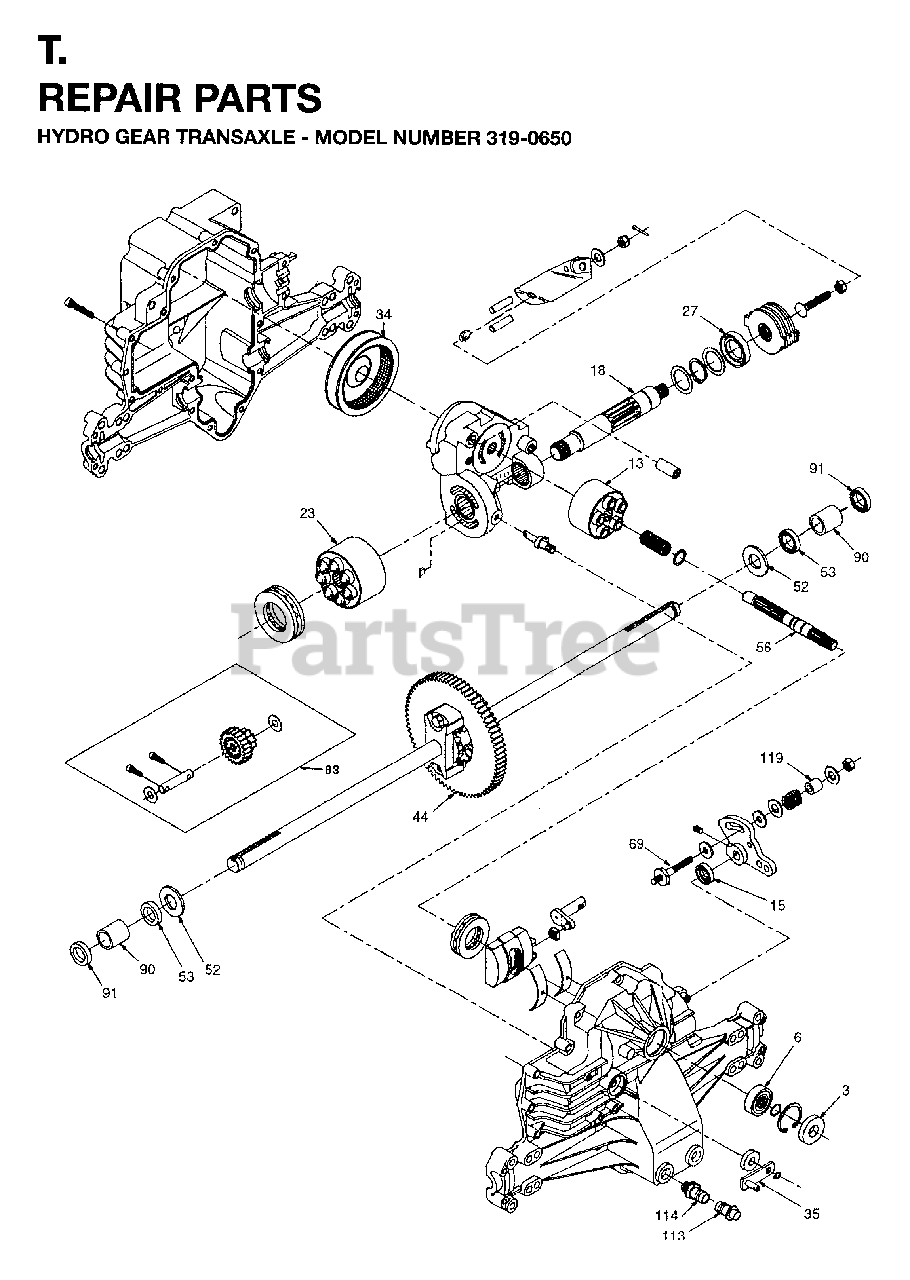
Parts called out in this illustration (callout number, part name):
6	BALL BEARING
13	BLOCK, CYL ASSY
18	SHAFT, MOTOR
23	BLOCK, CYL ASSY
34	ELEMENT, OIL FILTER
35	BYPASS ARM
44	DIFFERENTIAL ASSEMBLY
52	WASHER.HYDRO-GEAR
53	SEAL.HYDRO.45076
56	INPUT SHAFT
69	STUD 5/16-24
83	JACK SHAFT ASSY
90	SLEEVE BEARING
91	SEAL, WIPER
113	CAP, VENT ASSY
114	O-RING.ASM.70110
119	SPACER
